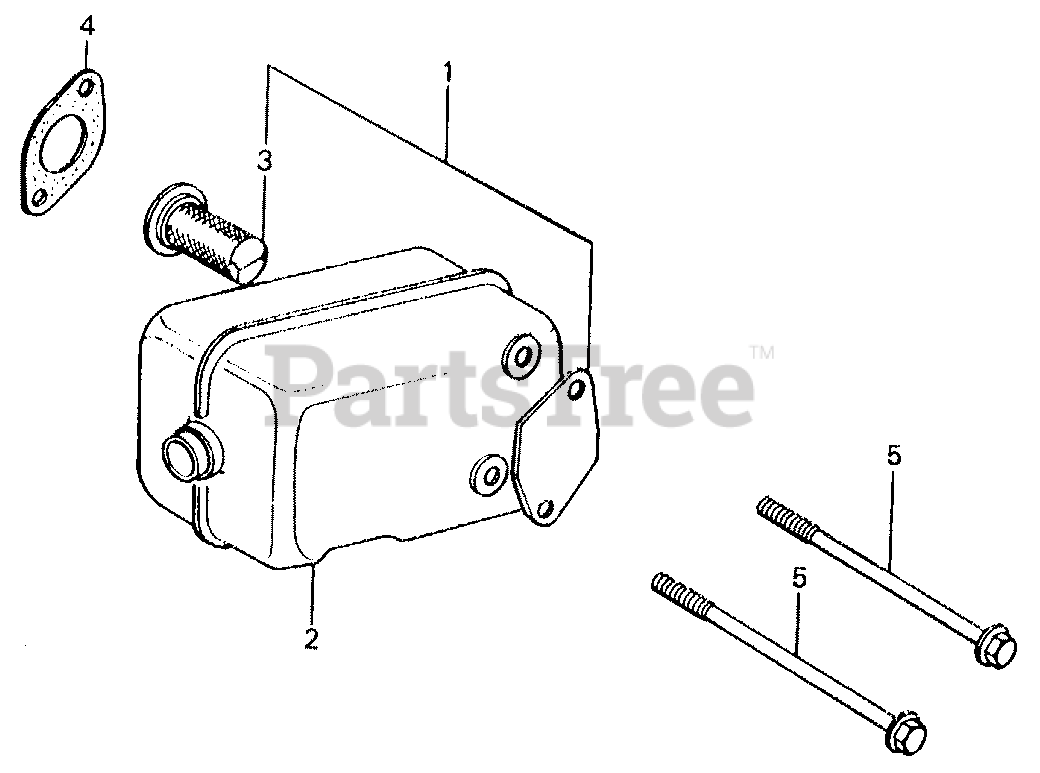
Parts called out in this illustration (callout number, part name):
1	ARRESTER KIT, SPARK
2	MUFFLER
3	ARRESTER KIT, SPARK
4	GASKET, MUFFLER
5	BOLT, FLANGE (8X104)
